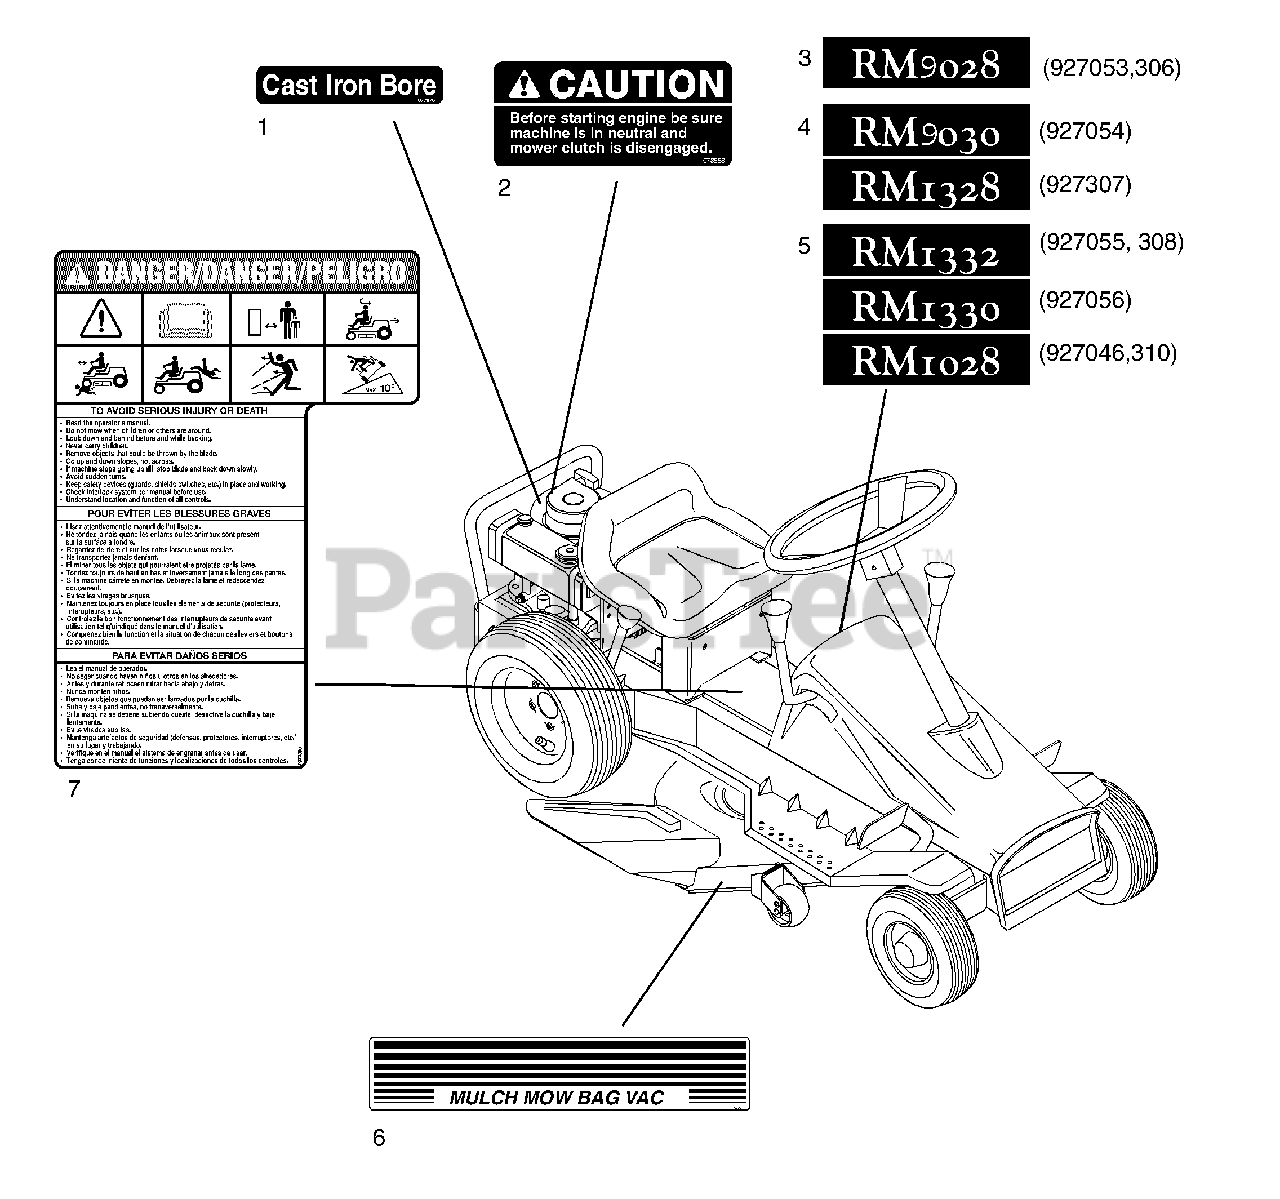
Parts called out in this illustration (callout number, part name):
1	DECAL - CAST IRON BORE
2	CAUTION DECAL - ENG. STARTING
3	DECAL - 9028
4	DECAL SET - RM DASH
5	DECAL-DASH RM SET
6	DECAL- MULCH-MOW-BAG-VAC
7	OPERATING INSTRUCTION DECAL
